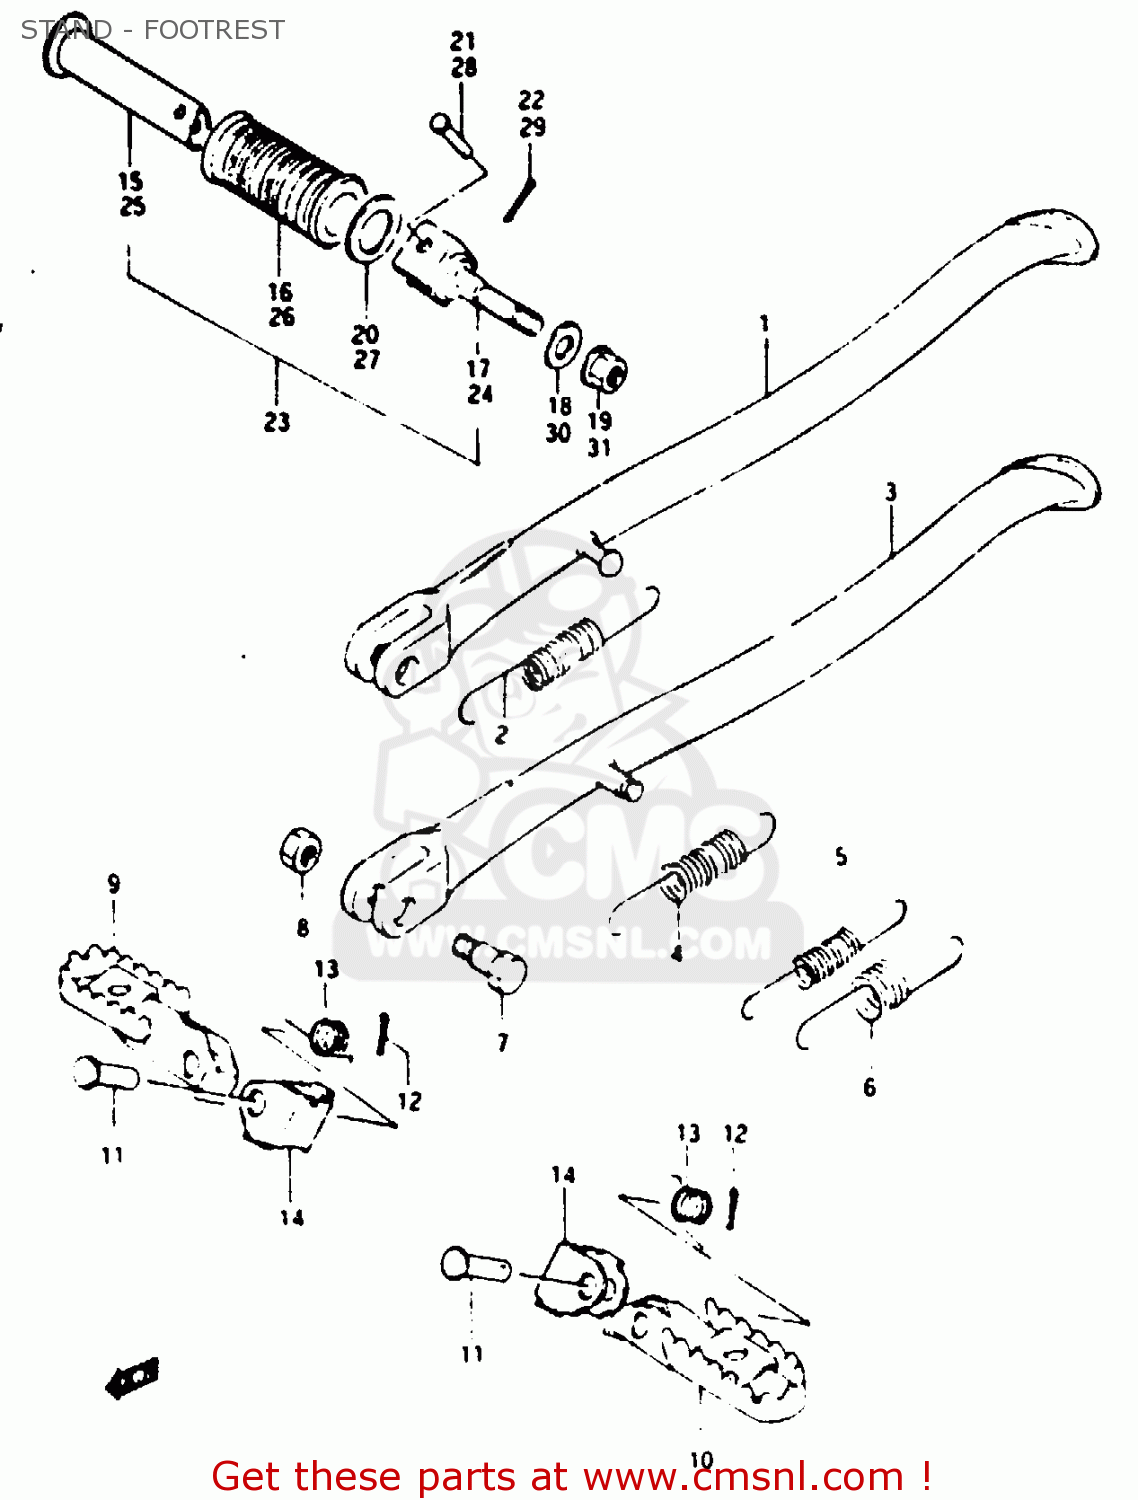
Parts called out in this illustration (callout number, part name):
1	STAND, PROP (BLUE)
2	SPRING
3	STAND, PROP (BLUE)
4	SPRING
7	BOLT L:30
8	NUT
9	FOOTREST,FR,R
10	FOOTREST, LH (BLUE)
11	PIN
12	PIN 25X20
13	SPRING
14	CUSHION,FR FOOTREST
15	BAR,PILLION FOOTREST
16	RUBBER,PILLION FOOTREST
17	HOLDER, PILLION FOOTREST
18	WASHER
19	NUT
20	WASHER (19.5X32X2)
21	PIN
22	PIN 25X20
23	FOOTREST ASSY,PILLION,R
24	HOLDER, PILLION FOOTREST
25	BAR,FOOTREST RUBBER
26	RUBBER,PILLION FOOTREST
27	WASHER (19.5X32X2)
28	PIN
29	PIN 20X20
30	WASHER
31	NUT
